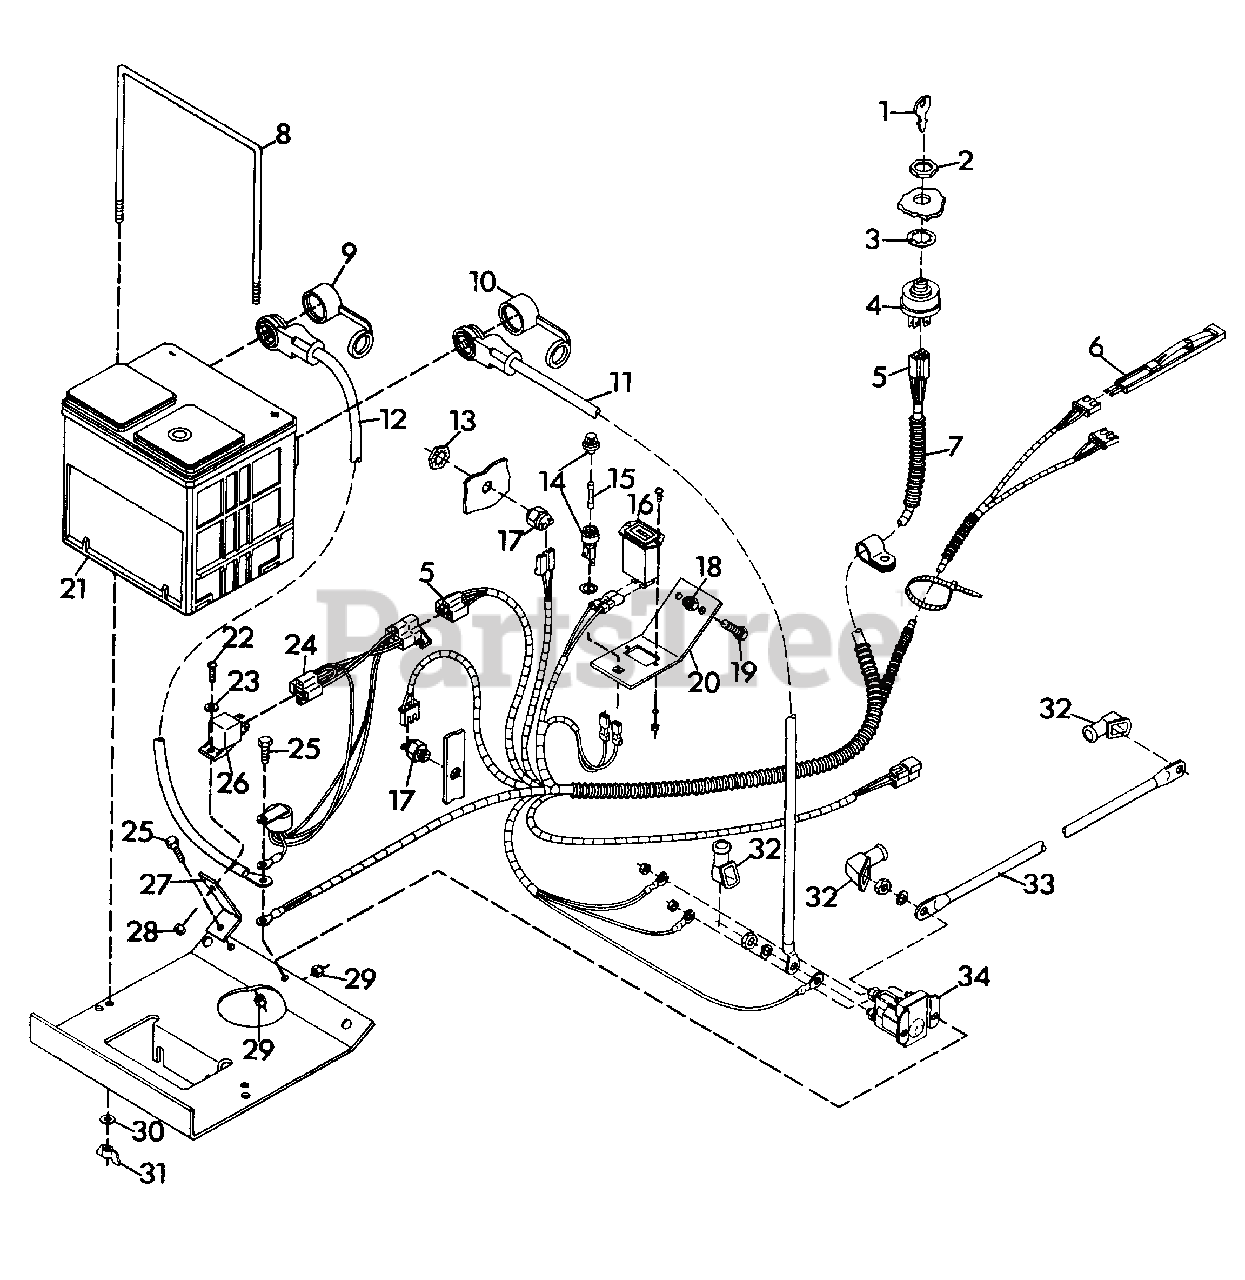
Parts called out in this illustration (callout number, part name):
1	KEY, IGNITION
2	NUT, JAM 9/16-24
3	WASHER, LOCK
4	SWITCH, IGNITION
5	CONNECTOR
6	SWITCH, SEAT
7	HARNESS, WIRING PRO MASTER-50
8	ROD, BATTERY
9	COVER, BATTERY NEG.
10	COVER, BATTERY POS.
11	CABLE, ELECTRICAL
12	CABLE, ELECTRICAL
13	NUT, STAMPED 9/16-18
14	FUSE, PANEL
15	FUSE, 25 AMP
16	HOURMETER
17	SWITCH, INTERLOCK
18	NUT, LOCK 3/8-16
19	BOLT, HEX 3/8-16X.875
20	BRACKET
21	BATTERY, DELCO MAINTENANCE-FREE #101 -REPLACEMENT BATTERY #83-50
22	SCREW, MACH. 10-24X.75 PHD
23	WASHER, FLAT .188X.438X.049
24	MODULE, TIME DELAY
25	BOLT, HEX 1/4-20X1.00
26	RELAY
27	BRACKET, FUEL LINE SUPPORT
28	NUT, LOCK 10-24
29	NUT, LOCK 1/4-20
30	WASHER, FLAT .281X.625X.065
31	NUT, WING 1/4-20
32	BOOT, BATTERY CABLE
33	CABLE
34	SWITCH, MAGNETIC
